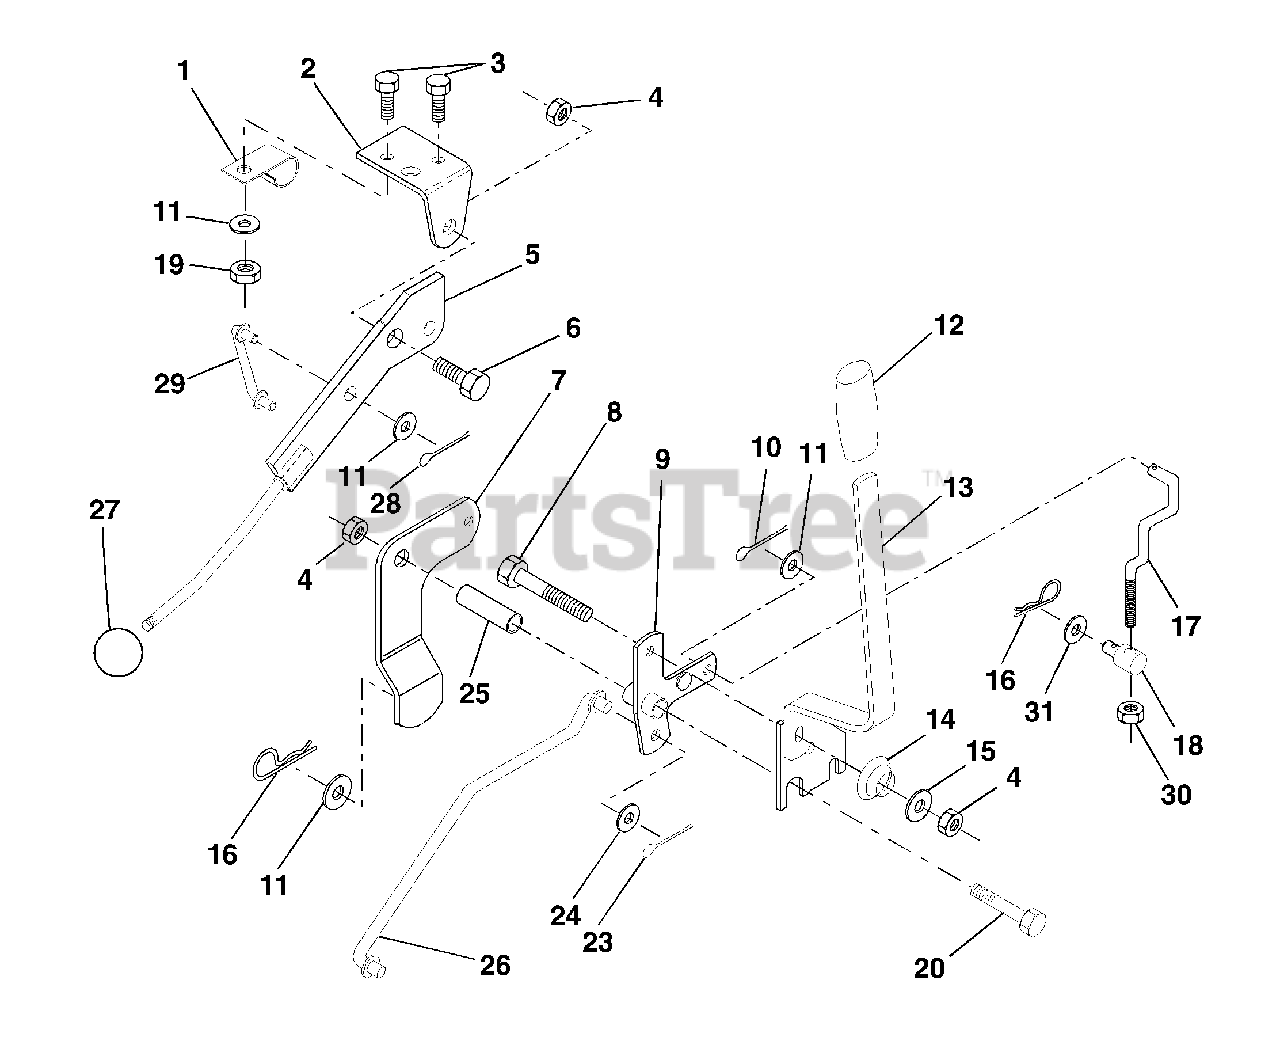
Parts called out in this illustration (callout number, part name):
1	Clip, Insulated
2	Bracket, Mower Clutch
3	Bolt, Fin. Hex 1/4-20 UNC x 1/2
4	Nut, Crownlock 3/8-16
5	Assembly, Clutch Lever
6	Bolt, Shoulder
7	Assembly, Mower Clutch Arm
8	Bolt, Hex 3/8-16 UNC x 2-1/4
9	Assembly, Bellcrank Lift
10	Pin, Cotter 1/8 x 3/4
11	Washer 13/32 x 13/16 x 16 Ga.
12	Grip, Handle
13	Assembly, Lift Handle
14	Spring, Compression
15	Washer 13/32 x 3/4 x 12 Ga.
16	Retainer, Spring
17	Link, Front Lift
18	Trunnion, Threaded 3/8-16
19	Nut, Keps 1/4-20
20	Bolt, Fin. Hex 3/8-16 UNC x 2-3/4
23	Pin, Cotter 1/8 x 1
24	Washer 17/32 x 1-1/4 x 12 Ga.
25	Tube, Spacer
26	Rod, Mower Lift
28	Pin, Cotter 3/32 x 3/4
29	Link, Mower Clutch
30	Nut Hex Jam 3/8-16 x 1.30
31	Washer 13/32 x 1 - 1/4 x 12 Ga.
